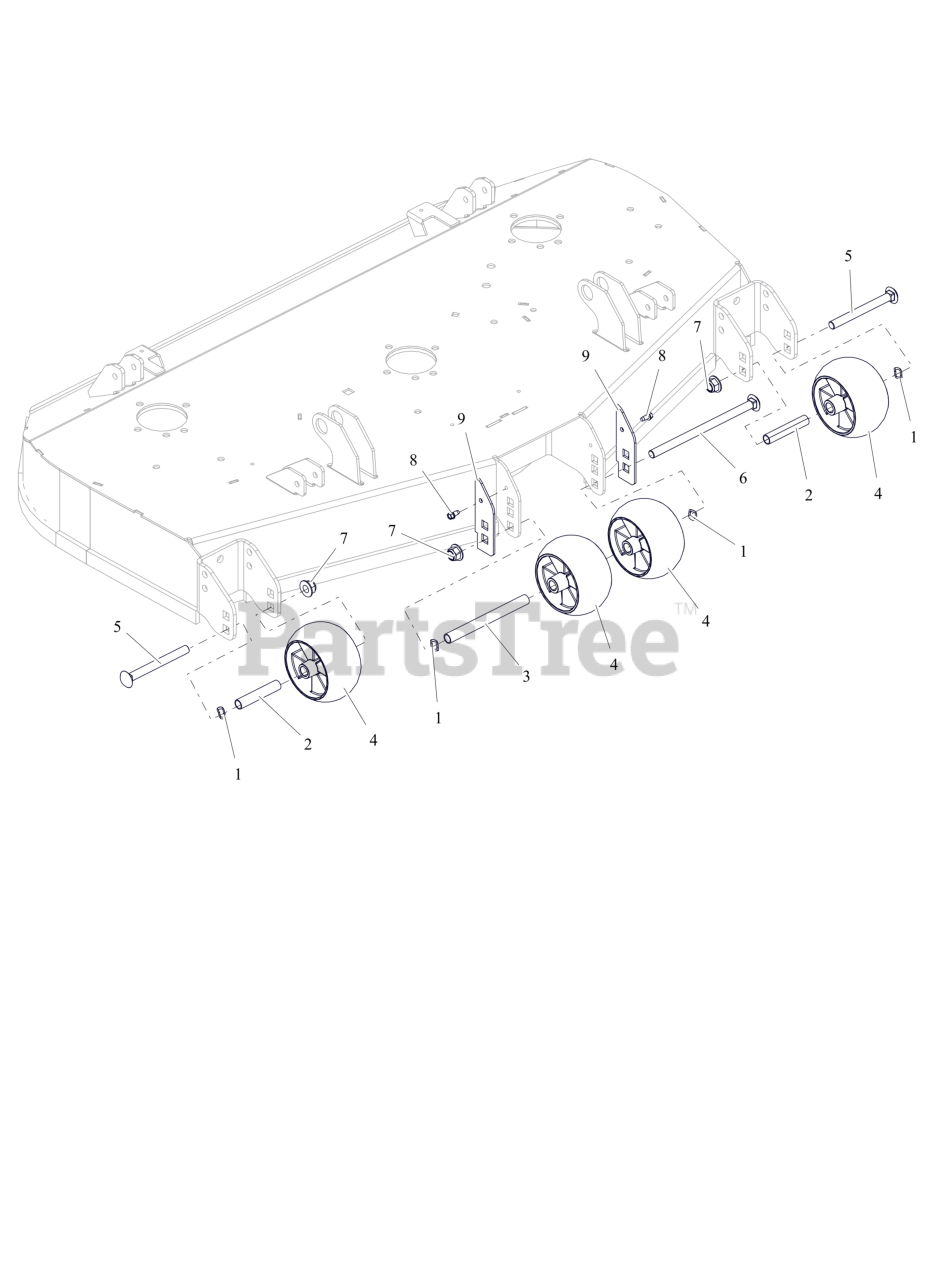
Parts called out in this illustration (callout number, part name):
1	WAVE WASHER .531X.781X.125FH
2	SPACER, .510X.625X3.35
3	SPACER, .510X.625X6.50
4	ANTI-SCALP WHEEL - 5X3 CTR
5	BLT, RHSN .50-13X5.00 G5 ZCC
6	BLT, RHSN .50-13X8.50 G5 ZCC
7	NUT,NYL-FLG .50-13 GF ZCC
8	SCR-TAP .25-20X.50 HWH ZCC
9	PLATE, ANTI SCALP WHEEL PLATE CE (ORANGE)
